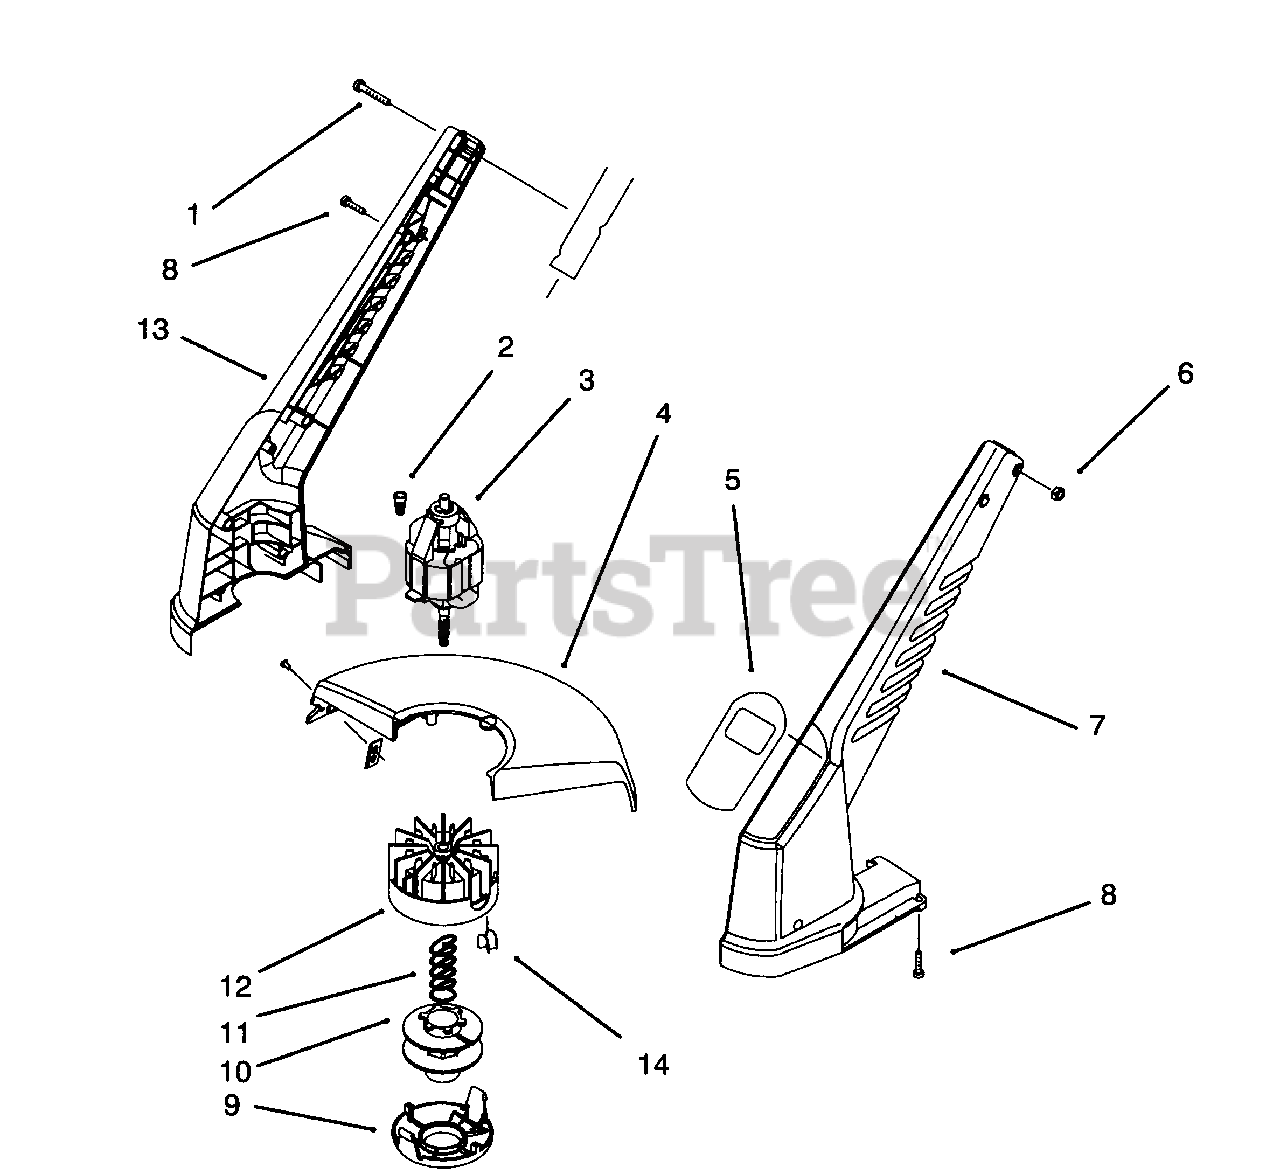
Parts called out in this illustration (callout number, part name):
1	Screw-Pan Hd.
2	Connector-Wire Nut
3	Motor Assembly (Incl. Ref. #12 & 14)
4	Shield-12"
5	Decal-12" Trimmer
7	Housing L.H.
8	Screw-Pan Hd. Tapping
12	Drum
13	Housing R.H.
